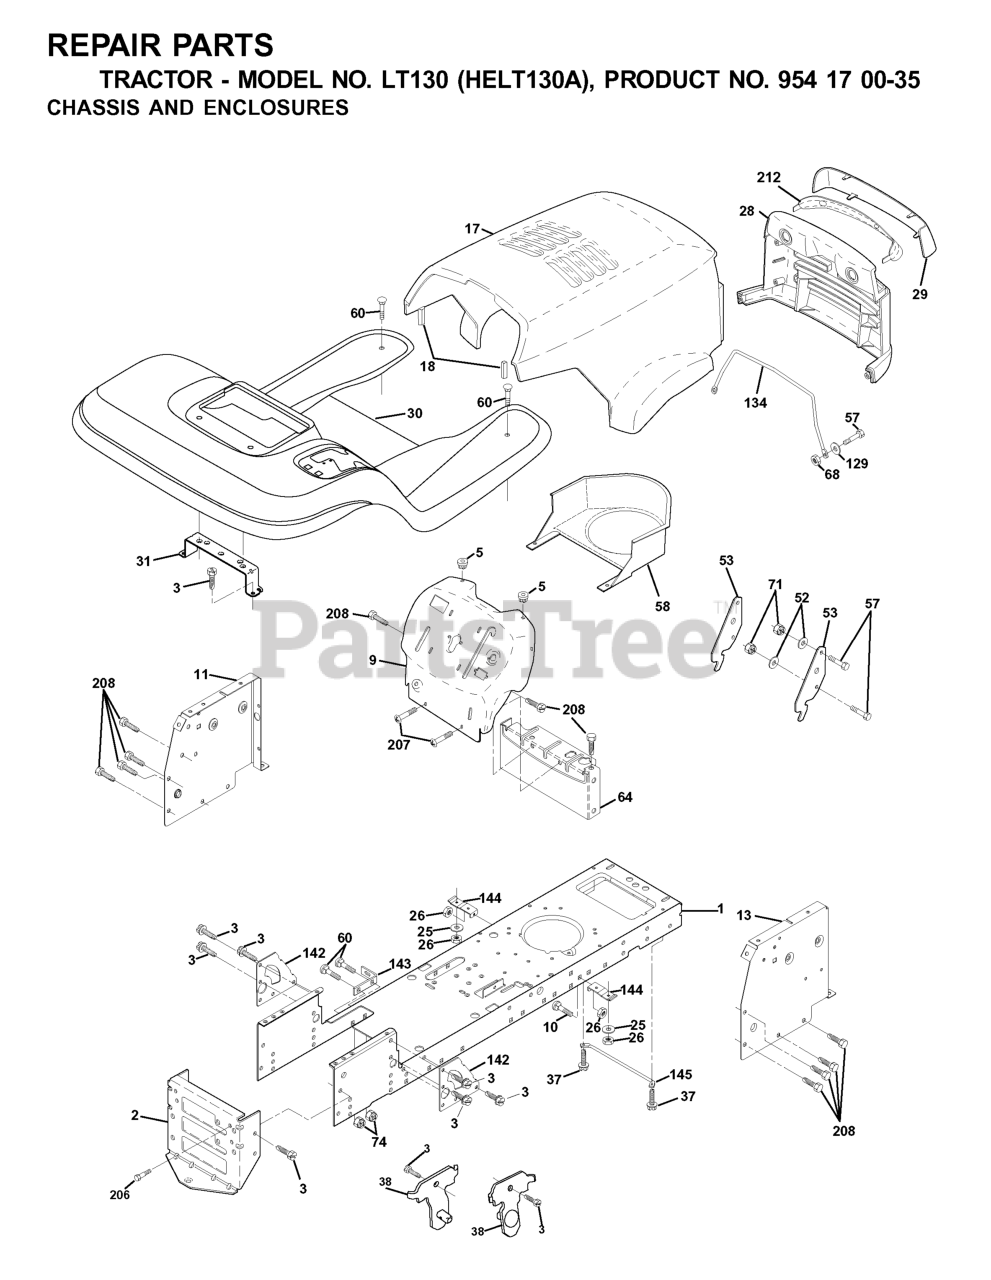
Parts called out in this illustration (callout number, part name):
2	DRAWBAR
3	SCREW 3/8-16X3/4
5	BUMPER.RUBBER.HOOD
9	DASH
10	BOLT D
11	PANEL DASH LH
13	PANEL DASH RH
17	HOOD
18	BUMPER HOOD T
25	WASHER
26	NUT
28	GRILL
29	LENS
30	FENDER FOOTREST
31	BRACKET.SUPPORT.FENDER
37	Screw 5/16-18 x 1/2 Hex, Self Tapping 5/16-18 x 1/2
38	BRACKET
53	BRACKET PNT PICK OFF LT/PL
57	BOLT
58	AIR DUCT P/L/LT
60	Bolt - Rd. Hd. Sq. Neckiage 3/8 16 x 3/4
64	DASH LOWER
68	NUT
71	NUT.CROWNLOCK.1/4
134	ROD SUPPORT HOOD LT/PL HUS.
142	PLATE
143	BRACKET, SWAY BAR
144	BRACKET FOOTREST
145	ROD PIVOT CHASSIS/HOOD
206	SHOULDER BOLT 5/16-18TT
207	SCREW, 5/16-18 X 1/2
208	SCREW 3/8-16X1/2
212	INSERT LENS REFLECTOR
